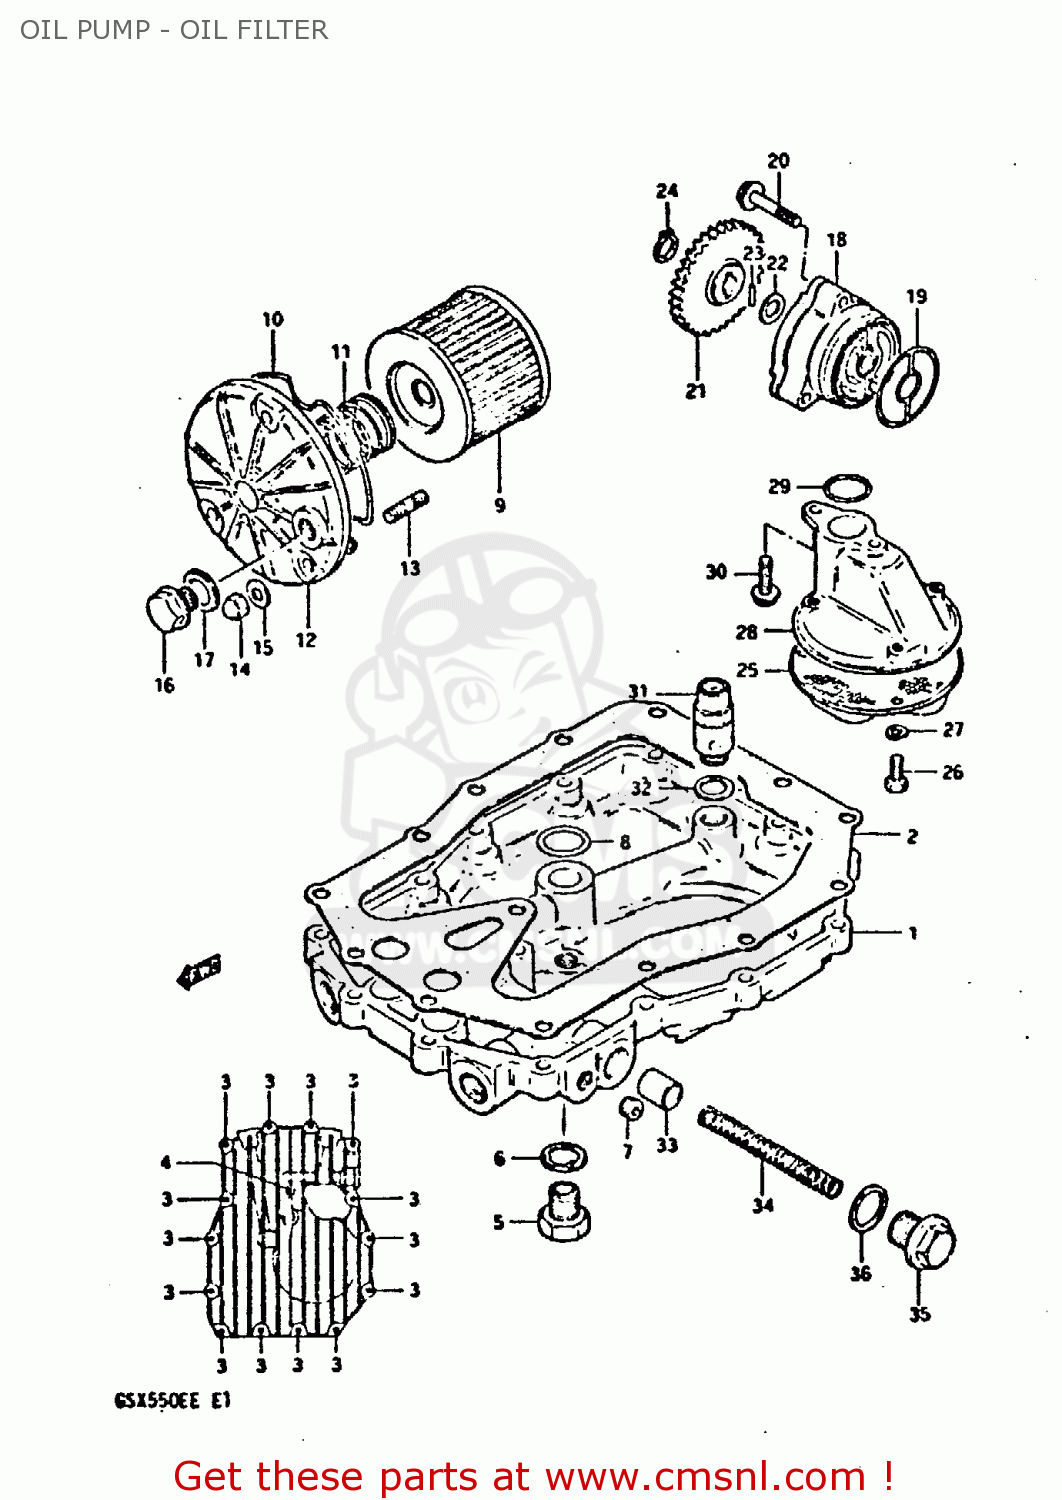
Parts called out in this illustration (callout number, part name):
1	PAN,OIL
2	GASKET,OIL PAN (MCA)
3	BOLT
4	BOLT 6X35
5	PLUG
6	GASKET(14X19.2X2) (NAS)
7	PLUG
8	O RING(D:3.2,ID:17.8)
9	FILTER ASSY,ENGINE OIL
10	O RING,OIL FILTER CHAMBER CAP
11	SPRING
12	CAP,OIL FILTER
13	STUD 6X20
14	NUT 6MM
15	WASHER
16	PLUG(14X12)
17	GASKET(14X19.2X2) (NAS)
18	PUMP ASSEMBLY,ENGINE OIL
19	O RING,OIL PUMP
20	BOLT(6X32)
21	GEAR,OIL PUMP DRIVEN
22	SHIM
23	PIN(4X15.8)
24	CIRCLIP
25	STRAINER,ENGINE OIL
26	BOLT
27	LOCK WASHER
28	PROTECTOR,OIL STRAINER
29	O RING(D:3.2,ID:17.8)
30	BOLT,REAR
31	REGULATOR ASSEMBLY,ENGINE
32	WASHER
33	PLUNGER,CONTROL
34	SPRING
35	PLUG
36	O RING(D:2.4,ID:16.8)
